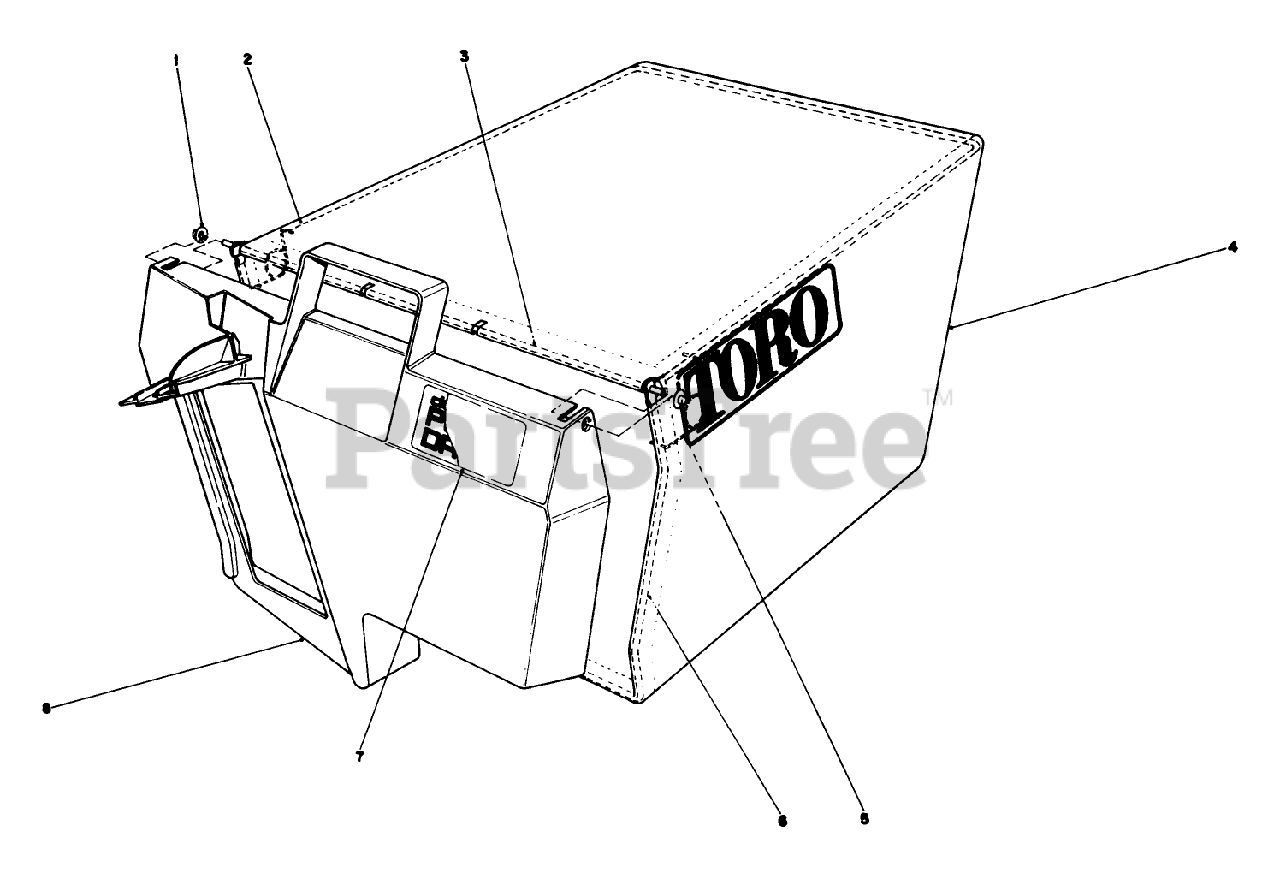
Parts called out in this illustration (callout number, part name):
1	NUT-PUSH
2	FRAME-BAG, UPPER
3	HINGE-DOOR, BAG
4	Bag
5	SPRING
6	FRAME-BAG
7	BAG DOOR DECAL
8	DOOR-BAG
